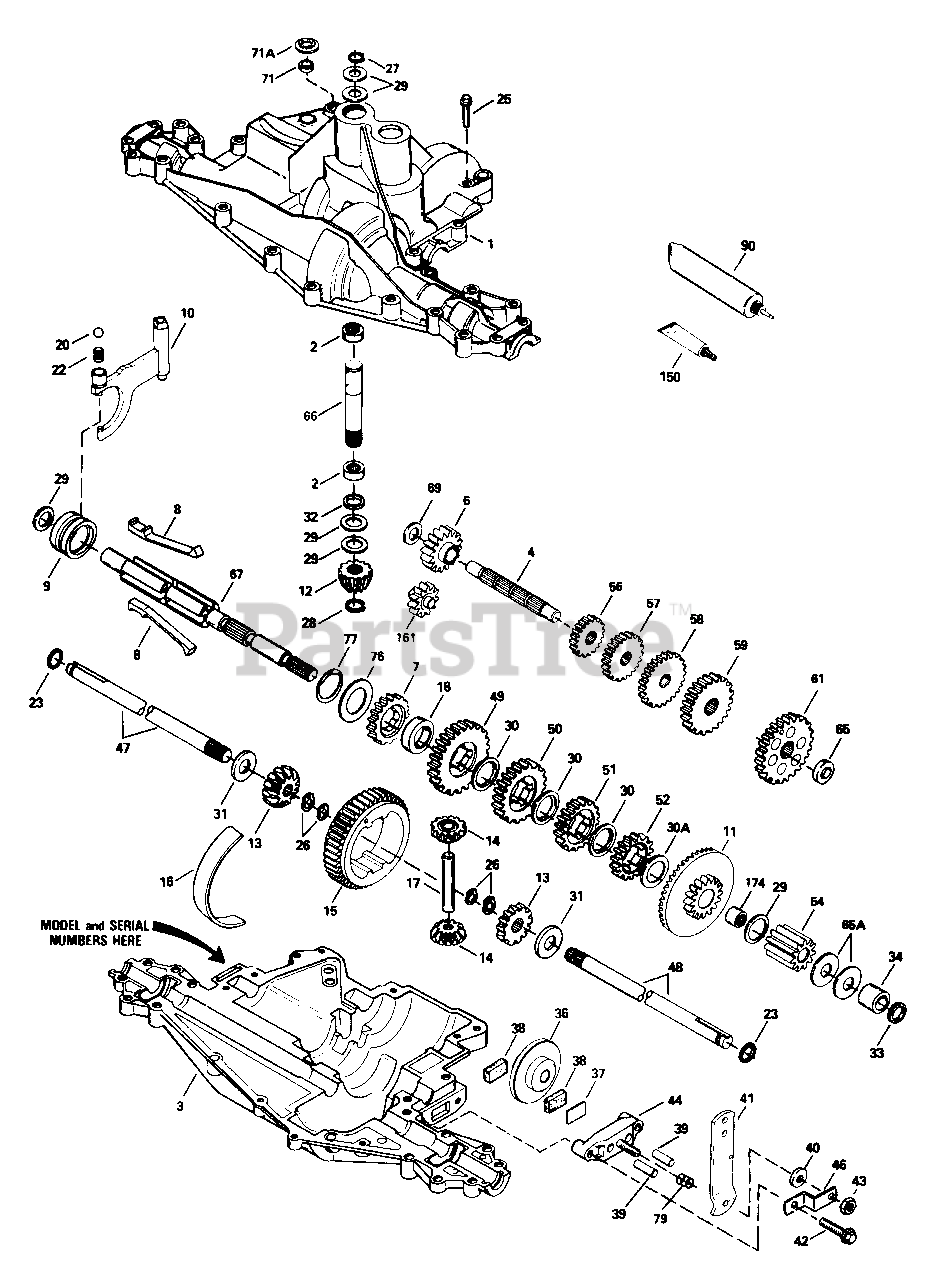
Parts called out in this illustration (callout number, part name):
1	Transaxle Cover
3	Transaxle Case
4	Countershaft
6	Spur Gear (16 Teeth)
7	Spur Gear (22 Teeth)
8	Shift Key
9	Shift Collar
10	Shift Rod & Fork
11	Bevel Gear & Bearing (44/16 Teeth)(Incl. Ref. #174)
12	Bevel Pinion (14 Teeth)
13	Bevel Gear (16 Teeth)
14	Differential Pinion
15	Ring Gear
16	Bearing Strip
17	Drive Pin
18	Neutral Spacer
20	Ball (3/8" dia.)
23	Seal Ring
26	Retaining Ring (pkg. of 2)
27	Retaining Ring
28	Retaining Ring
34	Bushing
36	Brake Disk
37	Brake Pad Plate
38	Brake Pad
39	Dowel Pin
41	Brake Lever
43	Locknut
44	Brake Pad Holder
46	Brake Lever Bracket
47	Axle (16-13/16" Lg.)
48	Axle (11-5/8" Lg.)(Incl. Ref. #26)
49	Spur Gear (35 Teeth)
50	Spur Gear (17 Teeth)
51	Spur Gear (19 Teeth)
52	Spur Gear (20 Teeth)
54	Spur Gear (11 Teeth)
56	Spur Gear (15 Teeth)
57	Spur Gear (23 Teeth)
58	Spur Gear (21 Teeth)
59	Spur Gear (30 Teeth)
61	Spur Gear (34 Teeth)
66	Input Shaft (3.522" Lg.)
67	Shifter & Brake Shaft
69	Thrust Washer
71	-Square Cut Ring
71A	Pushnut
77	Inverted Retaining Ring (pkg. of 2)
90	Grease (32 oz. btl. Bentonite grease)
150	Gasket Eliminator (Loctite #515)
161	Reverse Idler Assembly
174	Needle Bearing
